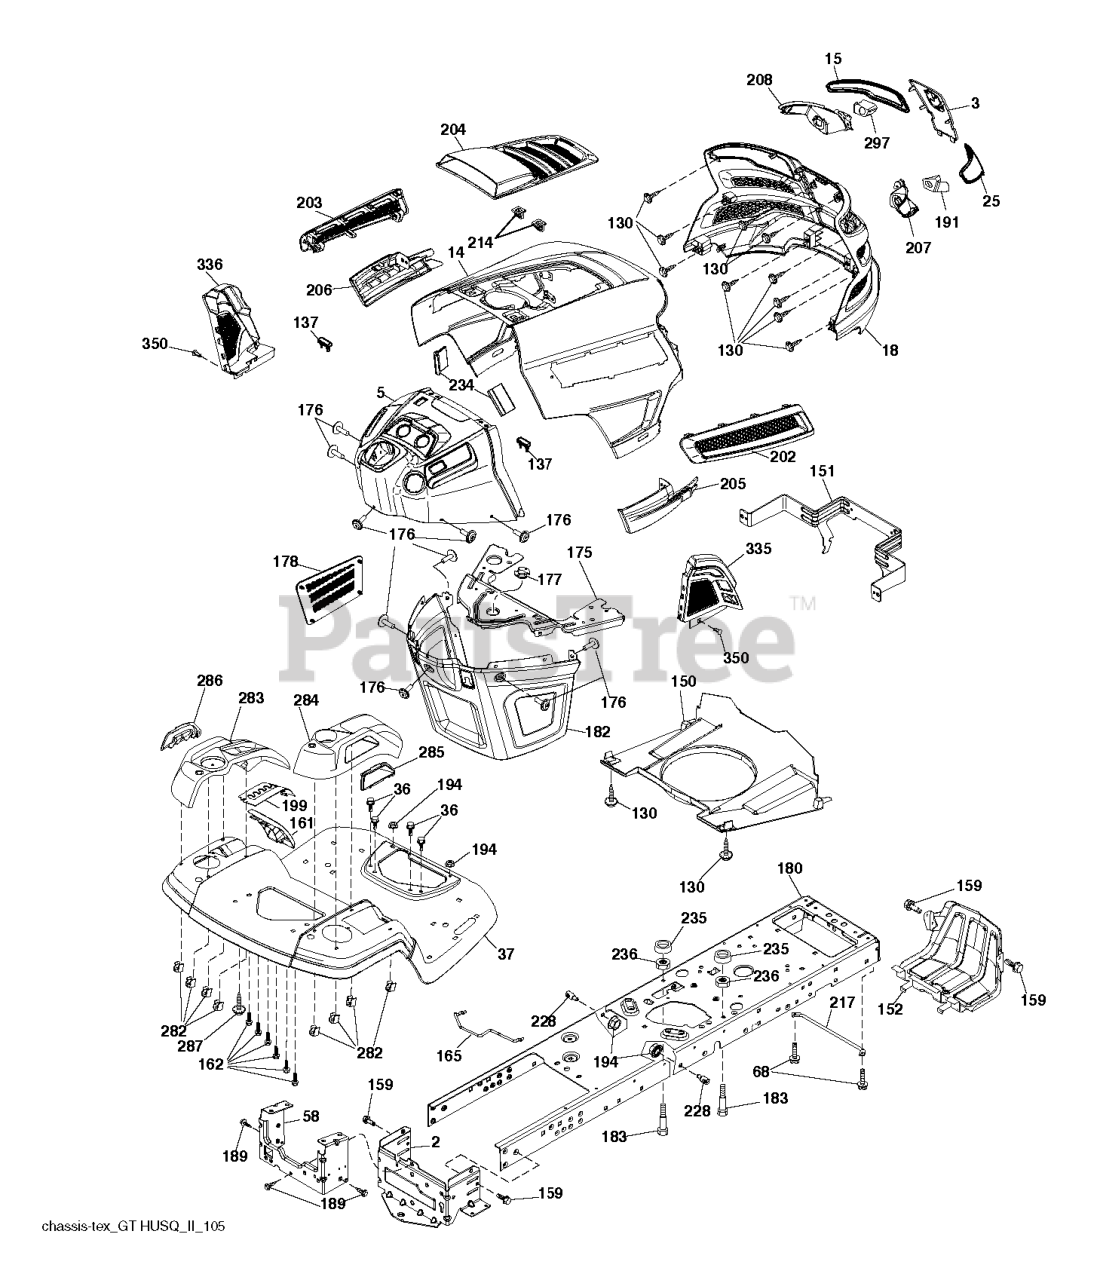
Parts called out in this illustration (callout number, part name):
2	DRAWBAR.LOWER.2PC.18/22
3	APPLIQUE.SUBASM.GT.HUSQ.II
5	DASH.UPP.GT2.DUAL.RD.PTO.MCHOK
14	HOOD.ASM.HUSQVARNA.GT.TEX.ORAN
15	LENS.HEADLIGHT.LH.GTII.2011
18	GRILLE.SUBSTRATE.2011.
25	LENS.HEADLIGHT.RH.GTII.2011
36	SCREW 5/16"
37	FENDER.TLT.FS.W/CPH/FW/RSF.668
58	DRAWBAR UPPER 2PC SMALL FENDER
68	Screw 5/16-18 x 1/2 Hex, Self Tapping 5/16-18 x 1/2
130	SCREW.#10 X 0.750.BOS
137	BUMPER DASH
150	AIR.DUCT.GTV.BLACK
151	BRACKET.PIVOT.HOOD.GT.HUSQ.II
152	SHIELD.BROWNING.PNT.GT.V2
159	SCREW, 3/8-16X3/4
161	WINDOW.FUEL.LT.HUSQ.TEX.418
162	SCREW.HI-LO.CONSOLE
165	SUPPORT.TANK.REAR.B/TE
175	PLATE.CROSSMEMBER.HUSQ
176	SCREW.#10-24X5/8.RN.QU
177	BUSHING, STEERING
178	CARGO.ASM.NET.TXGT.W/C
180	CHASSIS.STAMPING.LT/GT
182	DASH.LOWER.COMMON.12V.ADAPTOR
183	BOLT.5/16-18X1-1/4 FULL THD
189	SCREW
191	INSERT.REFLECTIVE.RH.HUSQ.GTII
194	NUT LOCK HEX FLANGE 5/16-18
199	PLATE.DECK.LIFT.HUSQ.LT
202	VENT.SIDE.RH.GT.HUSQ.II.
203	VENT.SIDE.LH.GT.HUSQ.II.498
204	VENT.TOP.HUSQ.GT2
205	SIDE.TRIM.RH.GT.HUSQ.II
206	SIDE.TRIM.LH.GT.HUSQ.II.GRAY
207	BEZEL LIGHT.RH.GT.II.MYLAR
208	BEZEL LIGHT.LH.GT.II.MYLAR
214	CLIP.RETAINER.TINNER.
217	ROD.PIVOT.HOOD
228	STUD.FASTNER.W/ANTI-ROTATE
234	BUMPER.HOOD.TEX.HUSQVARNA
235	SPACER FENDER
236	NUT.CENTERLOCK.5/16-
282	CLIP.RETAINER.CONSOLE.LT.HUSQ
283	CONSOLE.DECK.LFT.R.SDFL.HUSQLT
284	RP CONSOLE ASM.PDL CNTRL.HUSQ
285	CONSOLE INSERT RH
286	CONSOLE.INSRT.LH.HUSQ.LT.BLACK
287	SCREW 1/4X20
297	INSERT.REFLECTIVE.LH.HUSQ.GTII
335	COVER.LOWER.DASH.RH.BLACK
336	COVER.LH.CLOSE.OUT
350	CLIP.X-MAS.TREE
